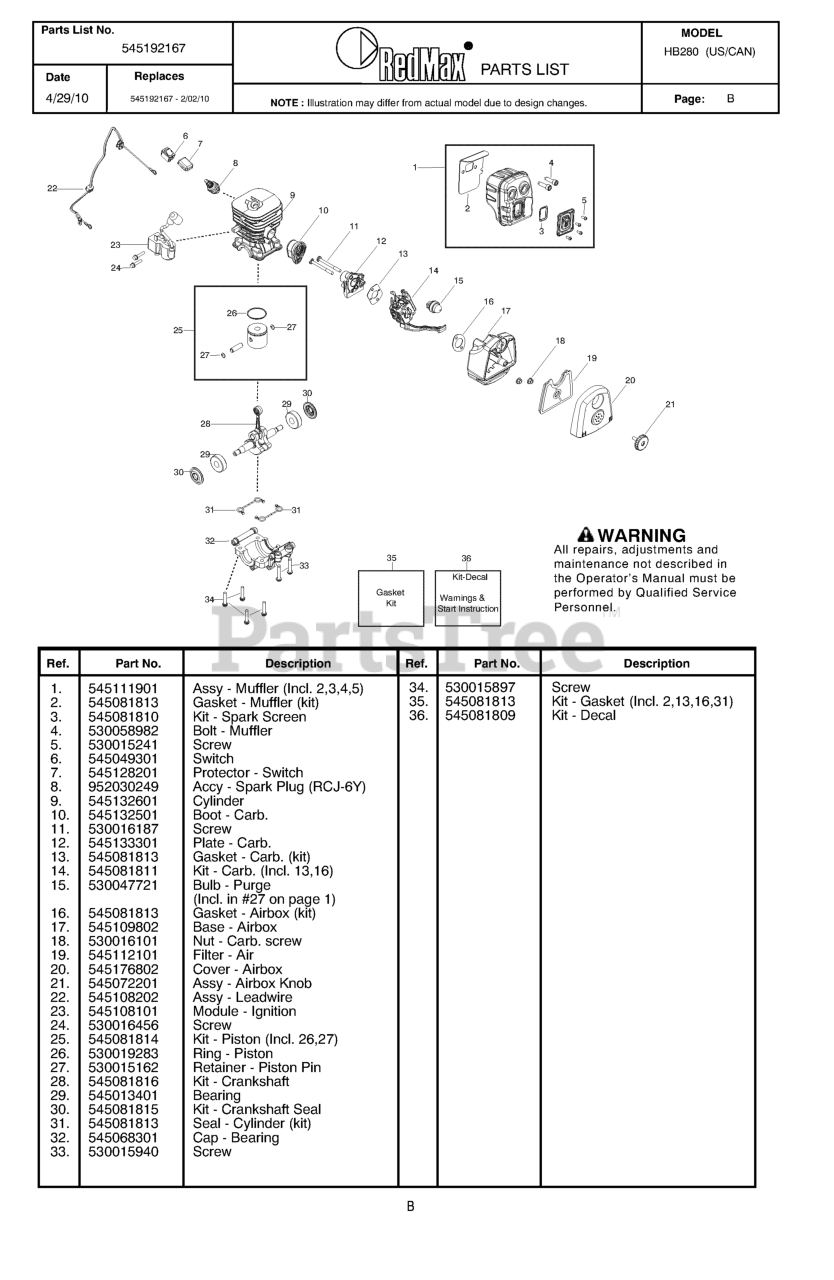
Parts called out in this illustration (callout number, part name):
1	ASS - MUFFLER (2,3,4,5)
2	GASKET - MUFFLER (kit)
3	KIT - SPARK SCREEN
4	BOLT - MUFFLER
7	PROTECTOR - SWITCH
8	ACCY - SPARK PLUG (RCJ-6Y)
9	CYLINDER
10	BOOT - CARB
12	PLATE - CARB
13	GASKET - MUFFLER (kit)
14	KIT - CARB (13,16)
15	BULB - PRIMER
16	GASKET - MUFFLER (kit)
17	BASE - AIR BOX
18	NUT - CARB SCREW
19	FILTER - AIR
20	COVER - AIR BOX
21	ASSY - AIR BOX KNOB
22	ASSY - LEAD WIRE
23	MODULE - IGNITION
25	KIT - PISTON (26,27)
26	RING - PISTON
27	RETAINER - PISTON PIN
28	KIT - CRANKSHAFT
30	KIT - CRANKSHAFT SEAL
31	GASKET - MUFFLER (kit)
32	CAP - BEARING
35	GASKET - MUFFLER (kit)
36	KIT - DECAL
